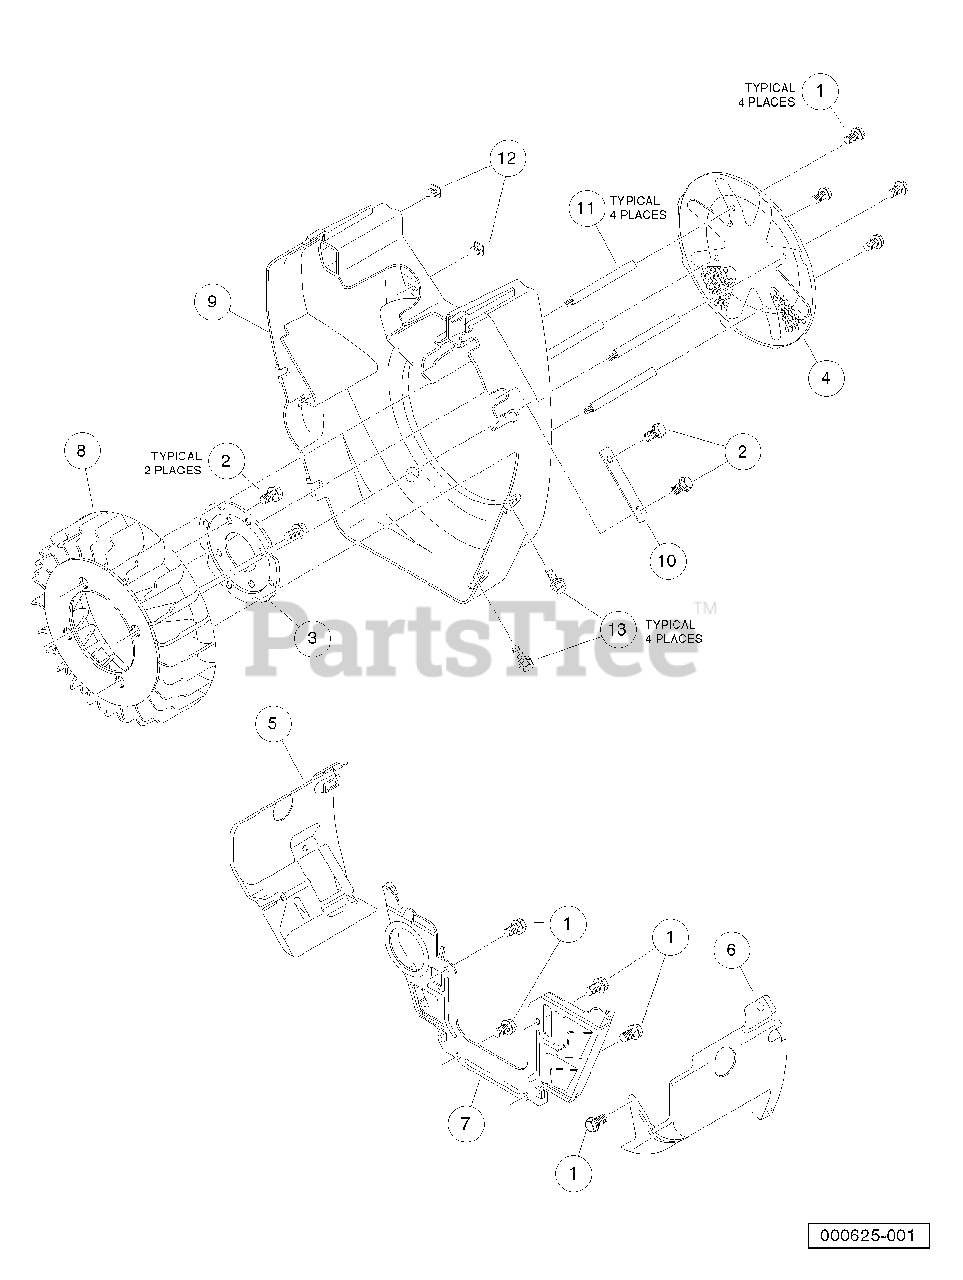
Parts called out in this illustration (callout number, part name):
1	Bolt, Flg, M6 X 1.0 X 12
2	Bolt, Flg, M6 X 1.0 X 16
3	Plate, Housing, Fan, Fh
4	Screen, Fan, Fh
5	Shroud, Engine, Rh, Fh
6	Shroud, Engine, Lh, Fh
7	Shroud, Engine, Front, Fh
8	Fan, Cooling, Fh
9	Housing, Engine, Fh
10	Washer, Housing, Fan, Fh
11	Stud, Fan Screen, Fh
12	Nut, Press In, Front Cover, Fh
13	Bolt, Oil Pickup, Fh
